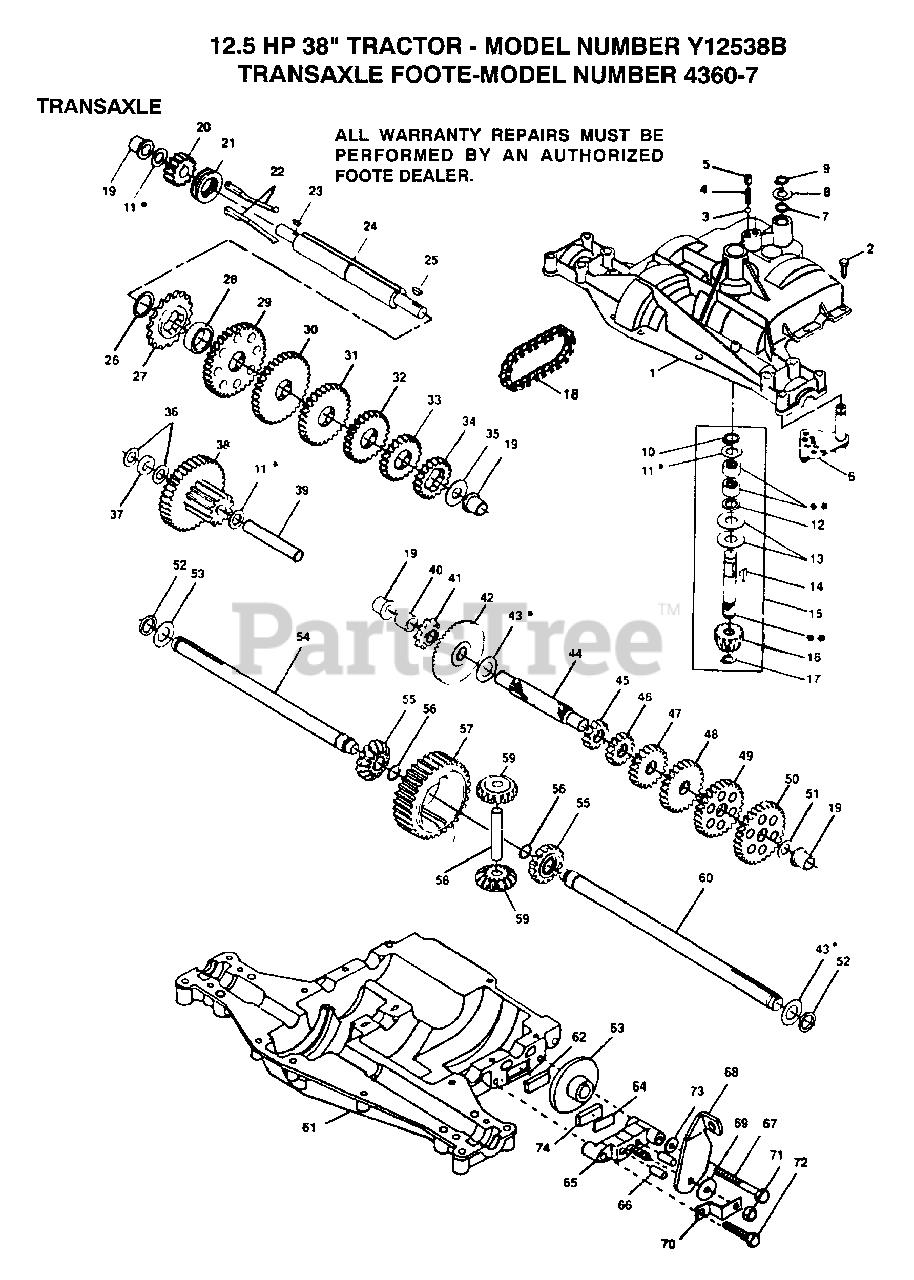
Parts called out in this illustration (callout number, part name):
1	HOUSING UPPER
3	BALL DETENT
4	SPRING, DETENT
5	SCREW, SET
6	ASSY SHIFTER
8	WASHER PLAIN
9	RING RETAINING
10	RING RETAINING
11	WASHER PLAIN
13	WASHER, PLAIN .632 X 1.38 X .046
14	KEY WOODRUFF #9
15	ASSY KIT INPUT SHAFT
16	PINION, BEVEL, 14 TEETH
17	RING, RETAINING
18	CHAIN, 24 PITCHES
19	BEARING, FLANGE
20	GEAR SPUR, 14 TEETH
21	COLLAR CLUTCH
22	KEY CLUTCH
23	KEY WOODRUFF #3
24	SHAFT INTERMEDIATE
25	KEY, WOODRUFF, #61
26	RING, RETAINING
27	SPROCKET, 18 TEETH
29	GEAR, SPUR, 37 TEETH
30	GEAR, SPUR, 35 TEETH
31	GEAR, SPUR, 30 TEETH
32	GEAR, SPUR, 25 TEETH
33	GEAR, SPUR, 22 TEETH
35	WASHER, PLAIN .640 X 1.37 X .061
36	WASHER, PLAIN .632 X 1.00 X .026
37	SPACER .630 X 1.00 X .169
38	ASSY GEAR COMB 12&35 TEETH
39	SHAFT IDLER
40	SPACER .635 X .875 X .755
41	SPROCKET, 9 TEETH
42	GEAR, BEVEL, 42 TEETH
43	WASHER PLAIN
44	SHAFT, DRIVE
45	GEAR, SPUR, 12 TEETH
46	GEAR SPUR, 15 TEETH
47	GEAR, SPUR, 20 TEETH
48	GEAR, SPUR, 25 TEETH
49	GEAR, SPUR, 28 TEETH
50	GEAR, SPUR, 31 TEETH
51	WASHER, PLAIN .632 X 1.00 X .060
53	WASHER PLAIN
54	AXLE LEFT HAND
55	GEAR, MITER, 15 TEETH
56	RING, RETAINING
57	GEAR, SPUR, 32 TEETH
58	SHAFT, CROSS
59	GEAR, MITER, 15 TEETH
60	AXLE, R.H.
61	HOUSING LOWER
62	PUCK, FRICTION
63	DISC, BRAKE
65	JAW, BRAKE
66	PIN, DOWEL
67	SCREW TAPPING
68	LEVER, ACTUATING
69	WASHER, PLAIN .321 X 1.00 X .055
70	BRACKET, ANTI-ROTATION
71	LOCKNUT 5/16-24
72	SCREW TAPPING
73	WASHER PLAIN
74	PUCK, FRICTION
